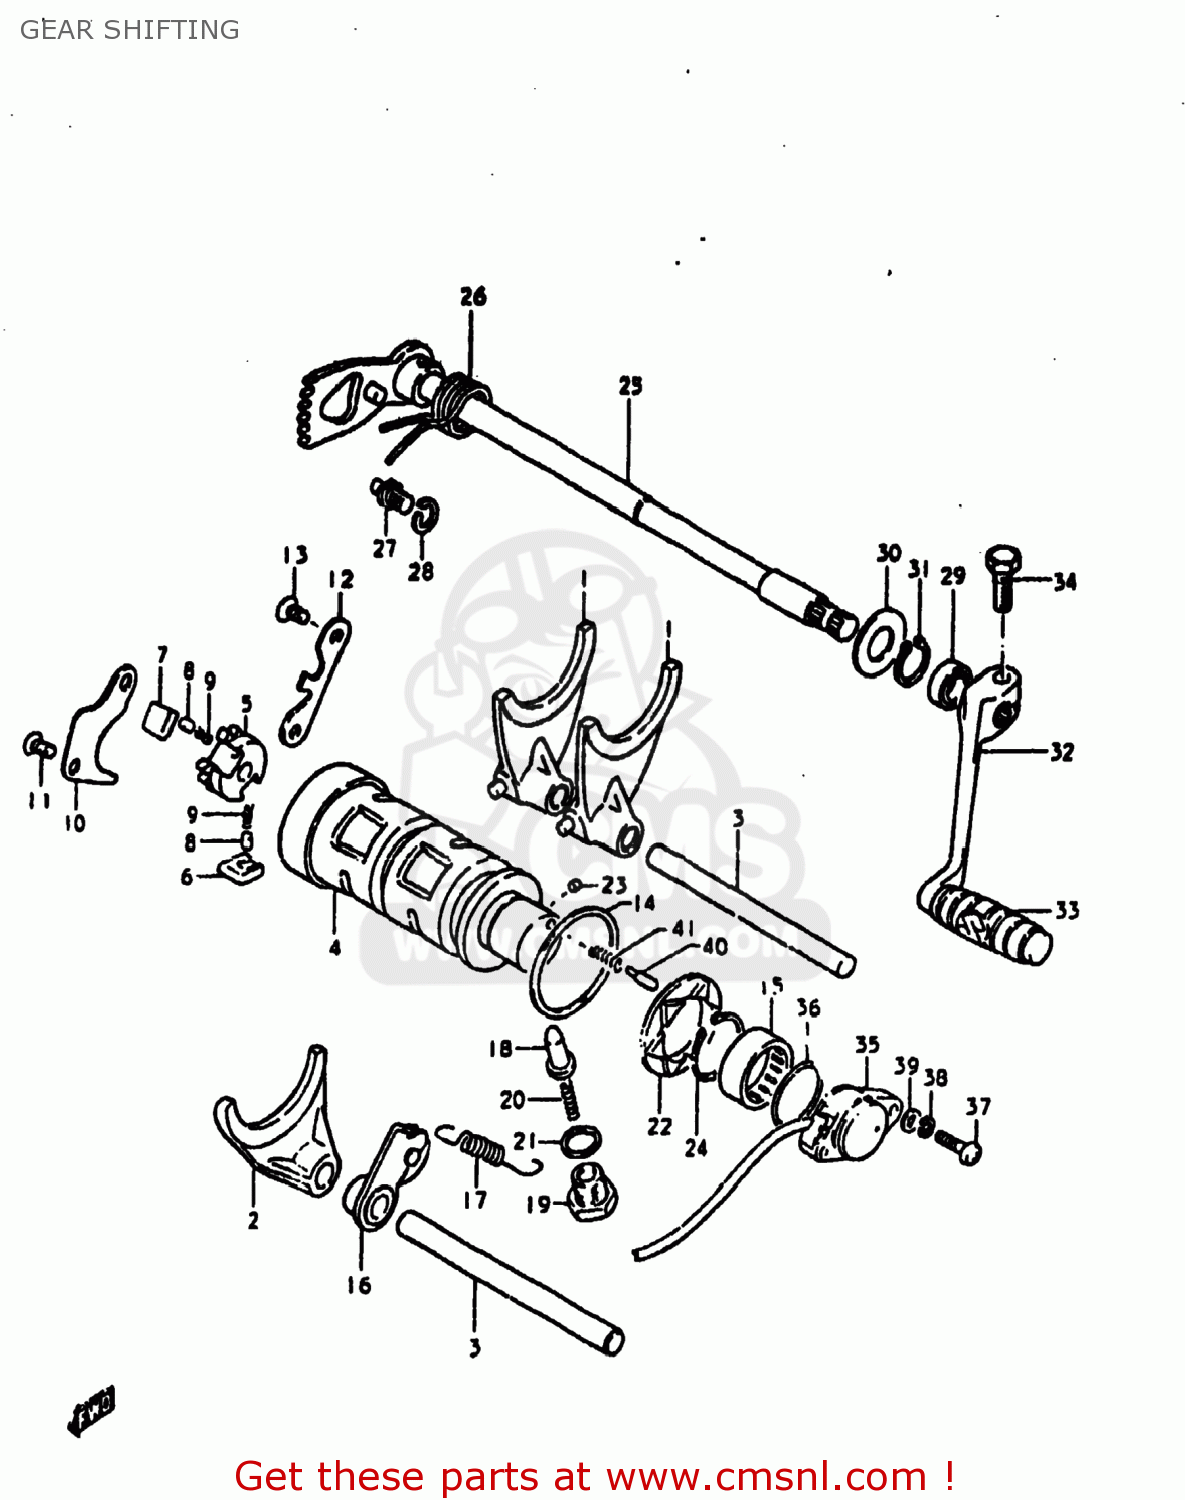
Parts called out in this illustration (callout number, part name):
1	FORK,GEAR SHIFT NO.1
2	FORK,GEAR SHIFT NO.3
3	SHAFT,GEAR SHIFT FORK
4	CAM,GEAR SHIFT
5	RETAINER,GEAR SHIFT CAM
6	PAWL,GEAR SHIFT NO.1
7	PAWL,GEAR SHIFT NO.2
8	PIN(5X8)
9	SPRING
10	LIFTER,GEAR SHIFT PAWL
11	SCREW
12	GUIDE,GEAR SHIFT CAM
13	SCREW
14	WASHER(40X45X1)
15	BEARING(25X32X12)
16	STOPPER,GEAR SHIFT CAM
17	SPRING
18	STOPPER,GEAR SHIFT CAM NO.2
19	HOLDER,GEAR SHIFT CAM STOP SPR
20	SPRING
21	GASKET(14X19.2X2) (NAS)
22	PLATE,GEAR SHIFT CAM STOPPER
23	PIN 4X6
24	CIRCLIP
25	SHAFT,GEAR SHIFT
26	SPRING
27	STOPPER,GEAR SHIFT CAM
28	WASHER
29	OIL SEAL
30	WASHER (12.5X27X1.6)
31	SPRING,RETAINER
32	LEVER ASSY,GEAR SHIFT
33	RUBBER,GEAR SHIFT PEDAL
34	BOLT
35	TERMINAL BASE,NEUTRAL SWITCH
36	O-RING (D:2.4 ID:26.2)
37	SCREW 5X20
38	LOCK WASHER
39	WASHER
40	PIN(5X15.5)
41	SPRING
